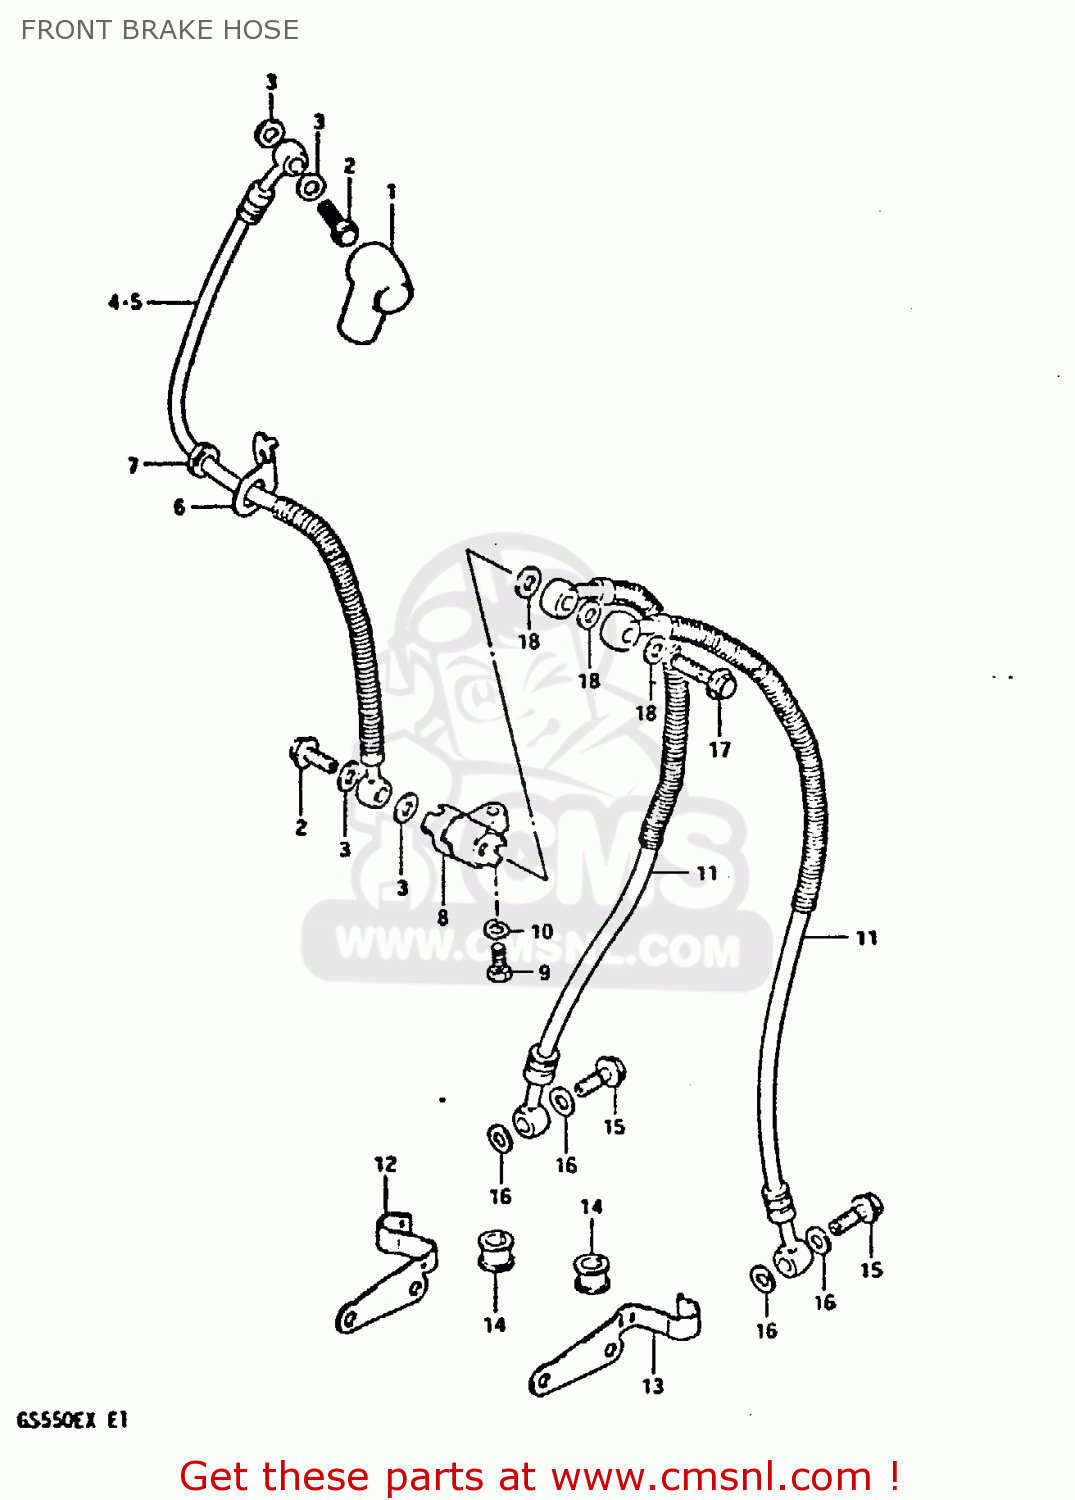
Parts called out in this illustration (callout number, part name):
1	BOOT,MASTER CYLINDER
2	BOLT,UNION
3	WASHER
4	HOSE,FRONT BRAKE
5	HOSE,FRONT BRAKE
6	GUIDE,BRAKE HOSE
7	GROMMET
8	JOINT,BRAKE HOSE
9	BOLT
10	LOCK WASHER
11	HOSE,BRAKE NO.2
12	CLAMP,FRONT BRAKE HOSE
13	CLAMP,FRONT BRAKE HOSE
14	BUSH,BRAKE HOSE GUIDE,NO.2
15	BOLT,UNION
16	WASHER
17	BOLT,UNION
18	WASHER
